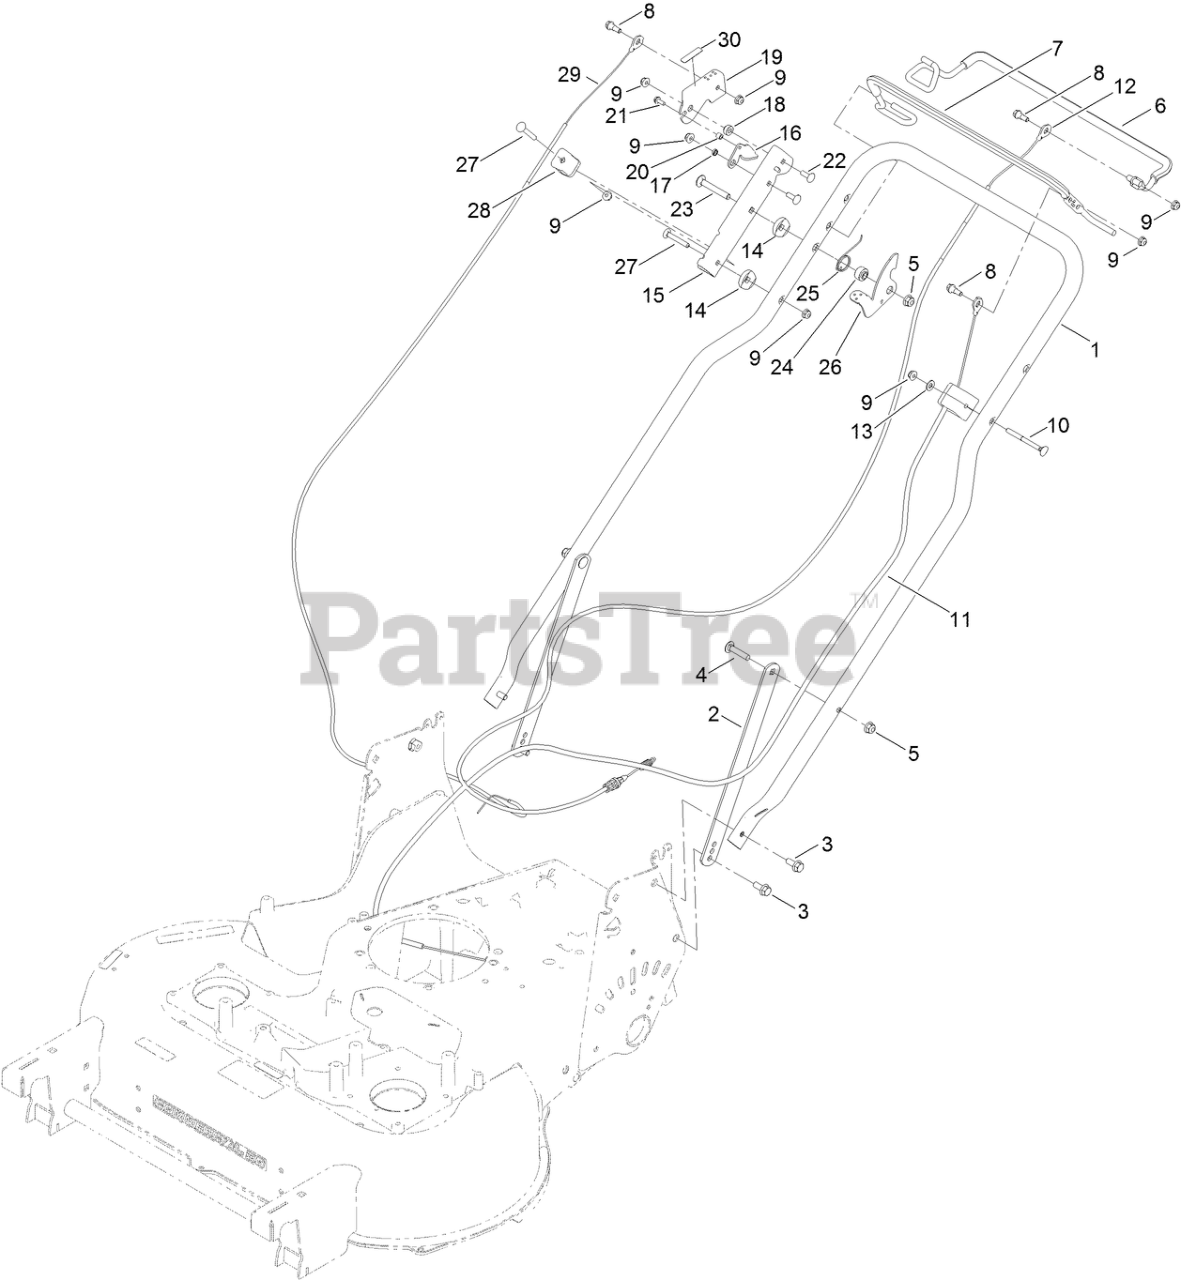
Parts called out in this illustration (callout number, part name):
2	SUPPORT-HANDLE
3	SCREW-HHF
4	BOLT-CARR
5	NUT-HF, NI
6	BAIL-TRACTION, COATED
7	BAIL-BBC, COATED
8	BOLT-SHOULDER
9	NUT-HF
10	SCREW-HANDLE
11	CABLE-BBC
12	CABLE-TRACTION
13	WASHER-FLAT
14	WASHER-CURVED
15	MOUNT-LEVER, BRAKE
16	LINK-ACTUATION, BRAKE
17	SPACER
18	WASHER-STEPPED
19	LEVER-BRAKE
20	SPACER
21	SCREW-TAPTITE
22	BOLT-CARR
23	BOLT-CARR
24	BUSHING-STEPPED
25	SPRING-LEVER, BBC
26	LEVER-BBC
27	SCREW-CARR
28	ANCHOR-CABLE
29	CABLE-BRAKE, PARKING
30	DECAL-BRAKE, PARKING
